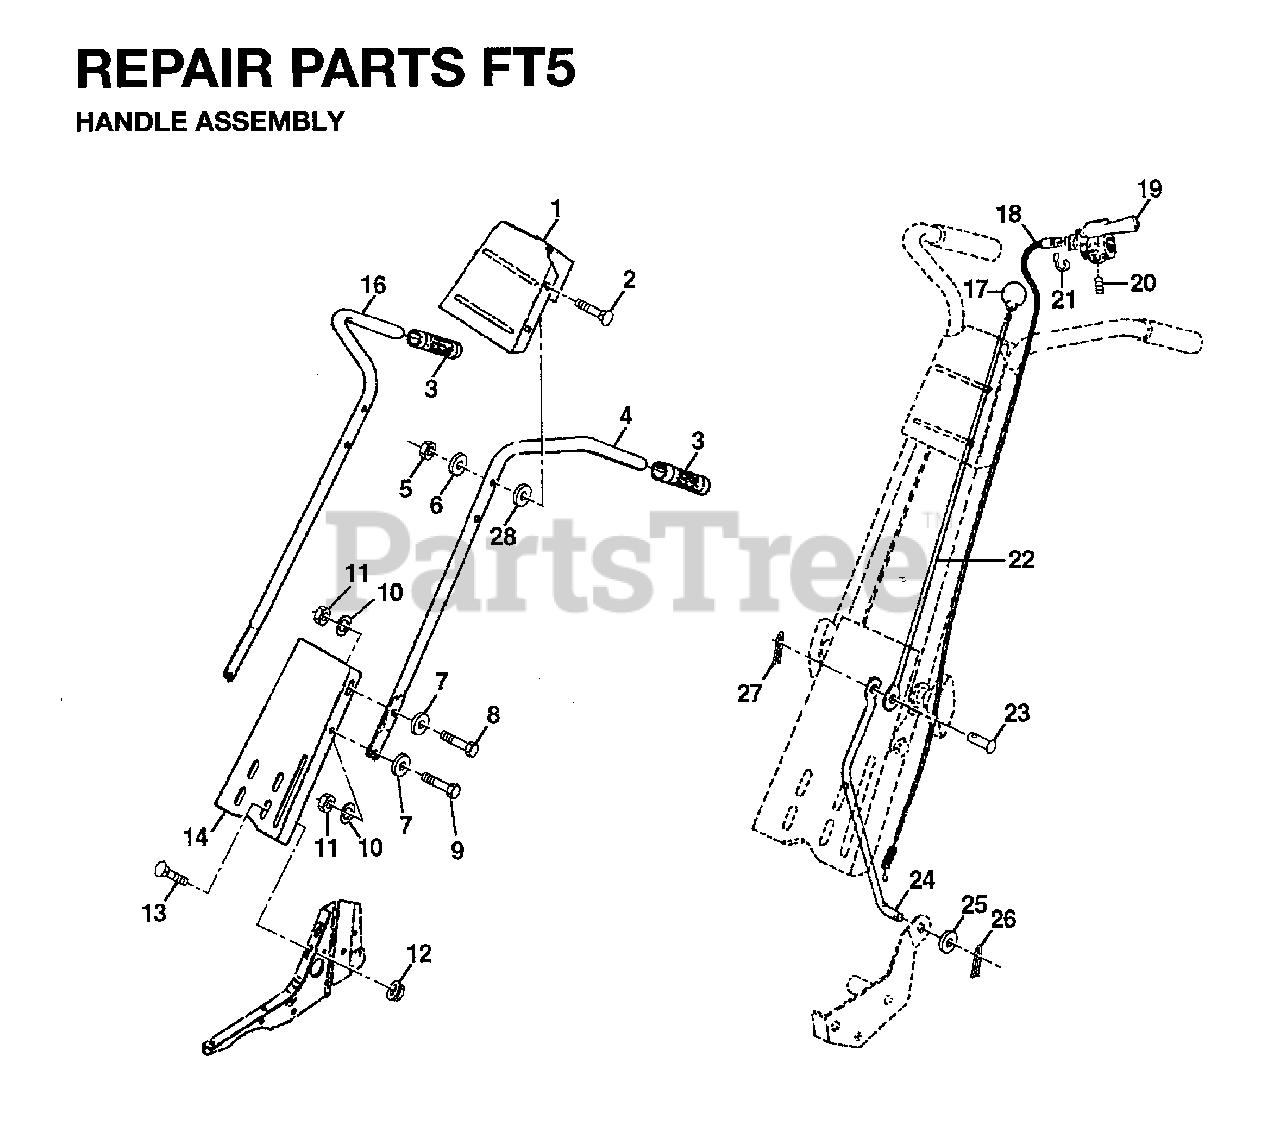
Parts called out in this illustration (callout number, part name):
1	SCREW
3	TIE CABLE CRT
4	GRIP T
5	RETAINER M
6	SHOULDER BOLT ST
7	SHIFT HANDLE CRT
8	GROMMET.RUBBER.CRT.TILLER
9	SHIFT ROD CRT
12	LOCKNUT
13	WASHER
14	LEVER.LOCK.CRT
16	LOCKWASHER
17	NUT
19	CABLE, CLUTCH 48 "Z"
20	CONDUIT CLIP T
22	GRIP BAR CRT(1)
23	CLAMP.BAR.CRT.BLACK
24	BAR ASSY CONTROL
25	CONT,THROTTLE
26	BOLT
27	GRIPS (2EACH)
28	BOLT.PIVOT
